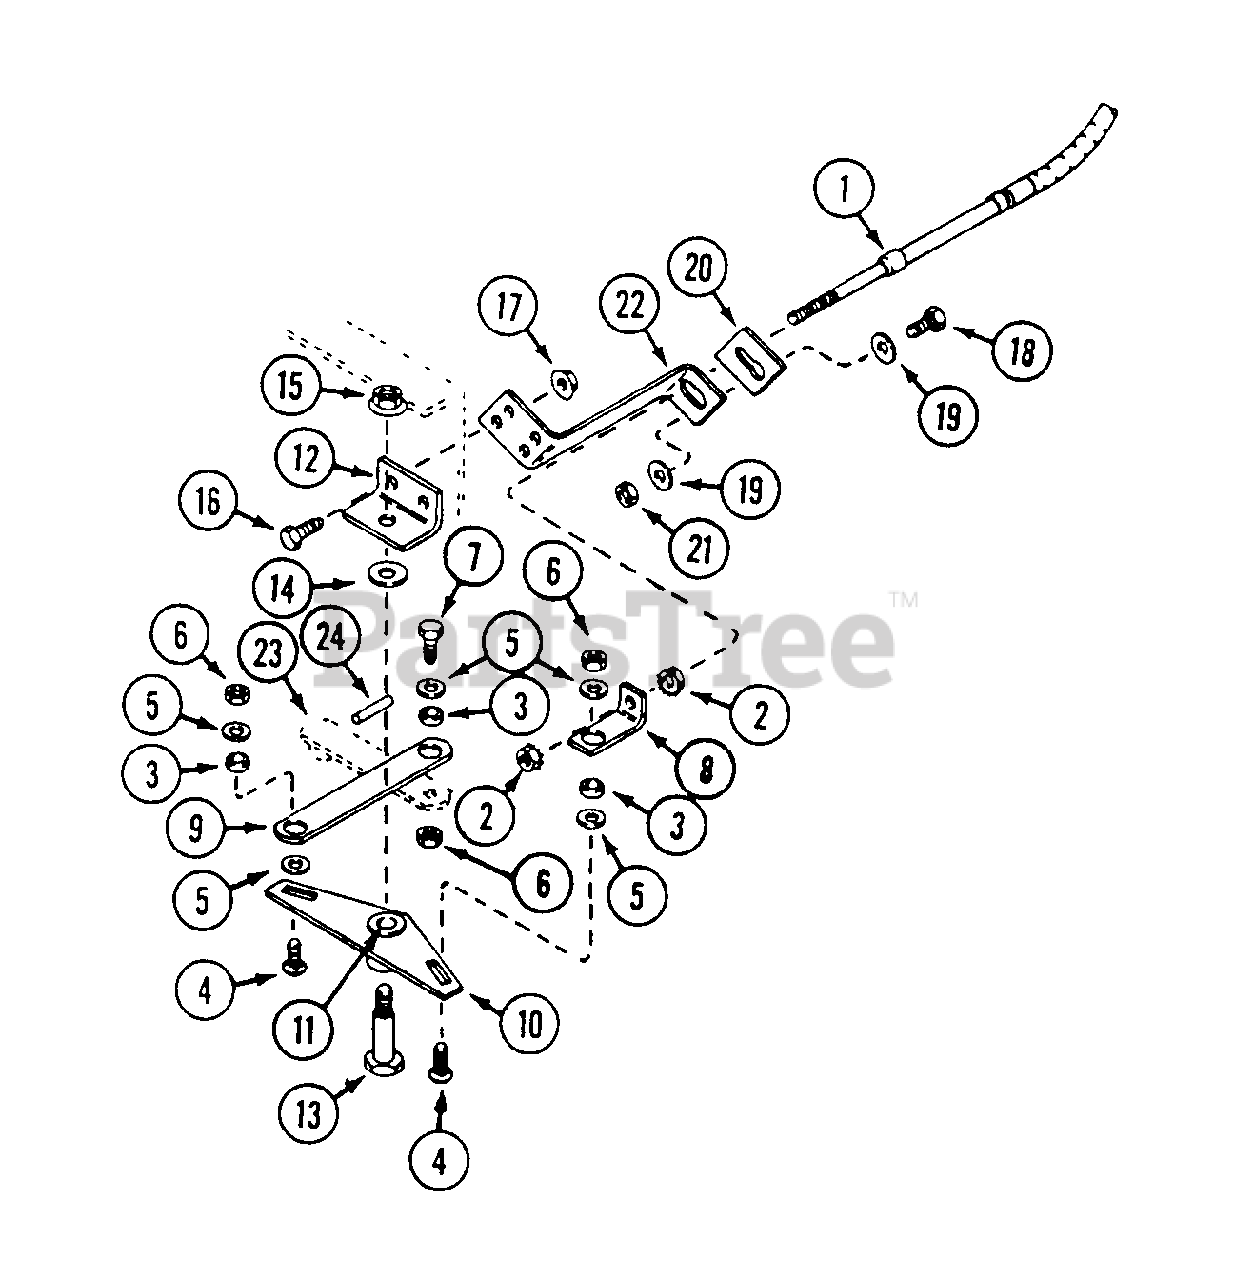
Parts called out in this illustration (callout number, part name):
1	CABLE - steering 46"
2	NUT - #10 - 32
3	BUSHING - steering cable
4	BOLT - 1/4" - 20 x 1" carriage
5	WASHER - 1/4"
6	NUT - 1/4" - 10
7	BOLT - 1/4" - 20 x 1"
8	BRACKET - steering cable end
9	LINK - control cable
12	BRACKET - bellcrank mounting
13	BOLT - shoulder
14	WASHER - 1/2"
15	NUT - 3/8" - 16 flange lock
16	BOLT - 5/16" - 18 x 1"
17	NUT - 5/16" - 18
18	BOLT - 1/4" - 20 x 1"
19	WASHER - 1/4"
20	PLATE - cable mounting
21	NUT - 1/4" - 20 lock
22	BRACKET - cable mounting
23	ARM - transmission
